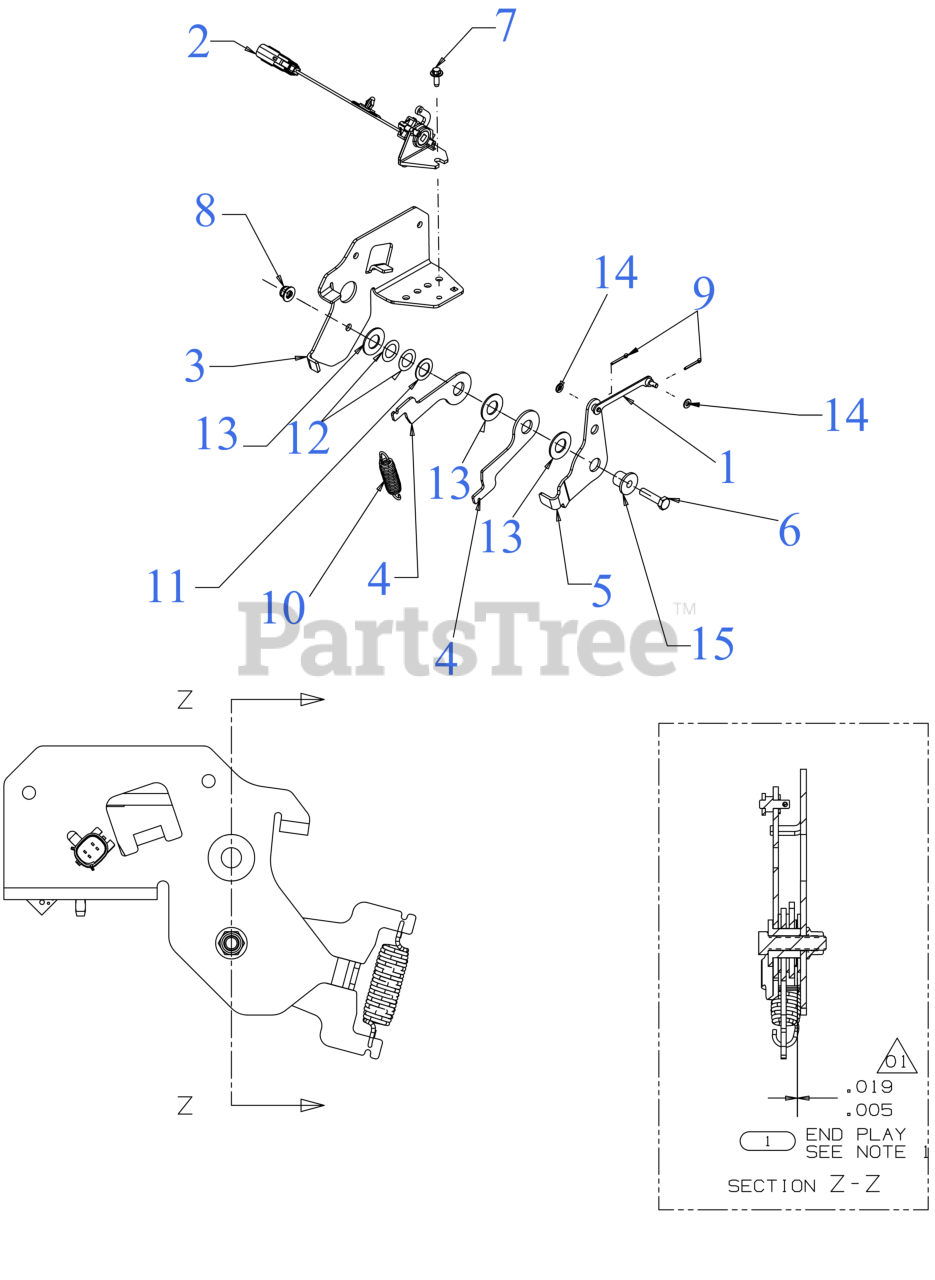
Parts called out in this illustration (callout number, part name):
1	CONTROL LINK (RH)
2	THROTTLE SENSOR ASSEMLBLY
2	HARNESS CLIP
2	ROTARY SENSOR MAGNET
3	CONTROL RETURN MOUNT (RH)
4	CONTROL RETURN PLATE
5	DRIVE CONTROL PLATE (RH)
6	SCREW 5/16-18 x 1.25 GR5
7	SCREW M6-1 x .625
8	FLANGE LOCK NUT 5/16-18
9	COTTER PIN 3/32
10	EXTENSION SPRING .65 OD x 2.65 LG
11	FLAT WASHER
12	SHIM WASHER .632X1.000X.010:HD
13	FLAT WASHER NYLON 5/8
14	FLAT WASHER .203 ID x .41 OD x .040
15	SHOULDER SPACER .32 x .625 x .66
